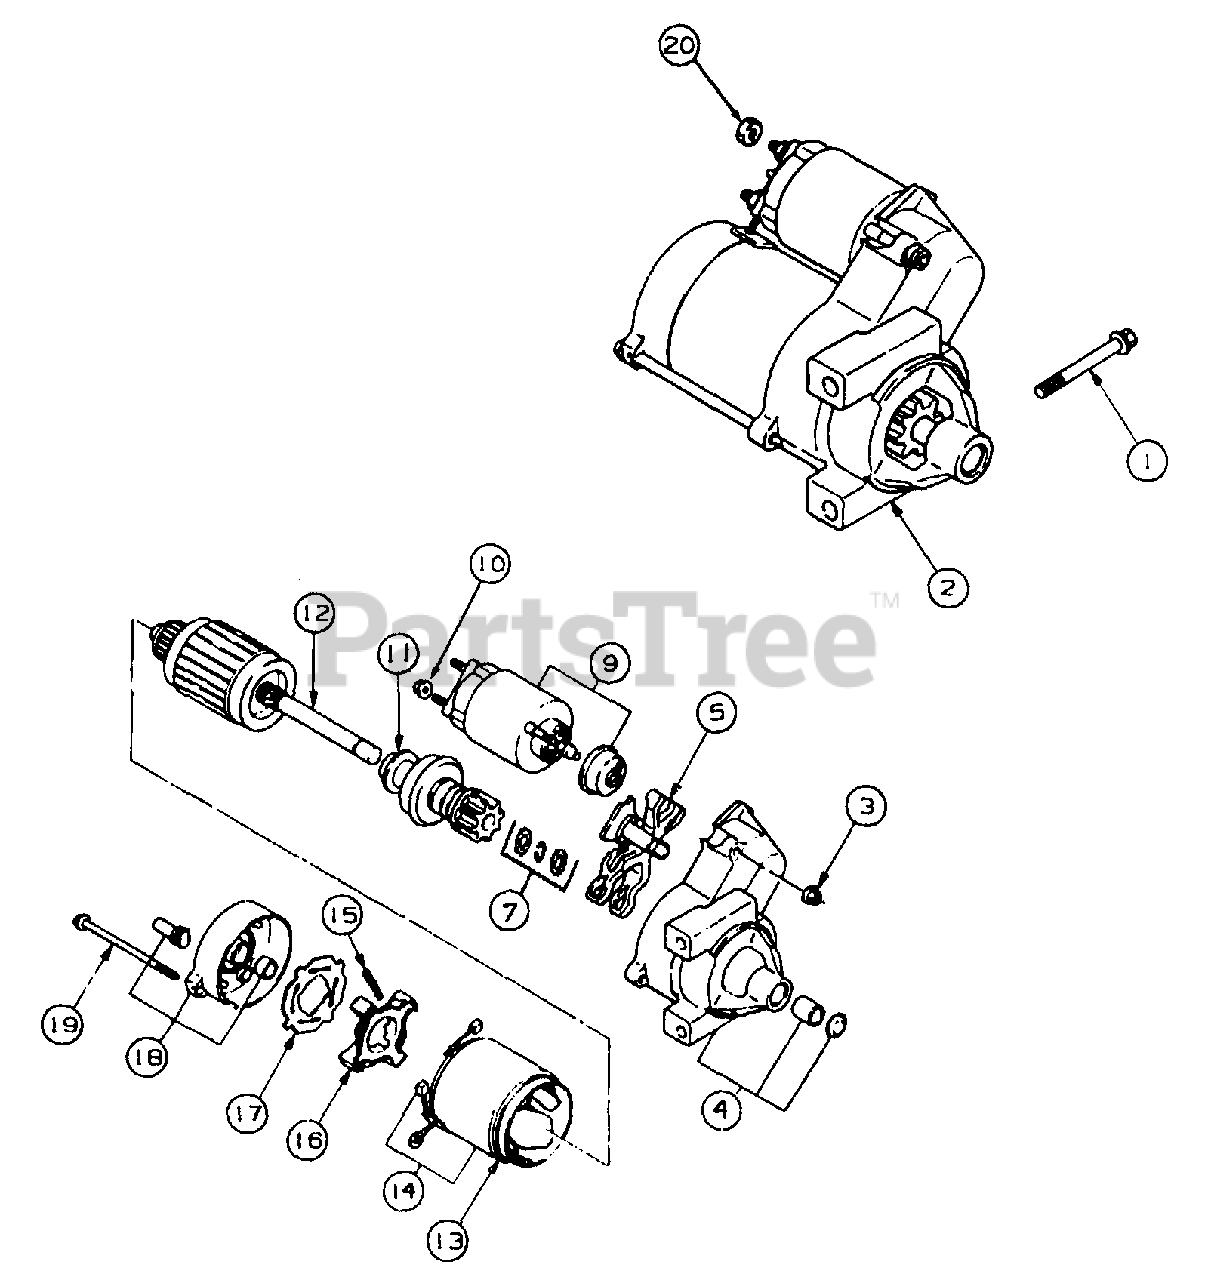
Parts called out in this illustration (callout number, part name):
1	Screw, Bendix, M8 x 1.25 x 80.6
2	Starter, Solenoid Shift Assy
3	Nut, Starter
4	Cap, Drive End
5	Lever, Starter Drive
7	Kit, Starter Repair
10	Nut, Starter
11	Drive Pinion
12	Armature, Starter
14	Kit, Brush
15	Spring, Brush
16	Holder, Brush
18	Cap, Commutator End
20	Nut, Hex Flange, M8 x 1.25 1
